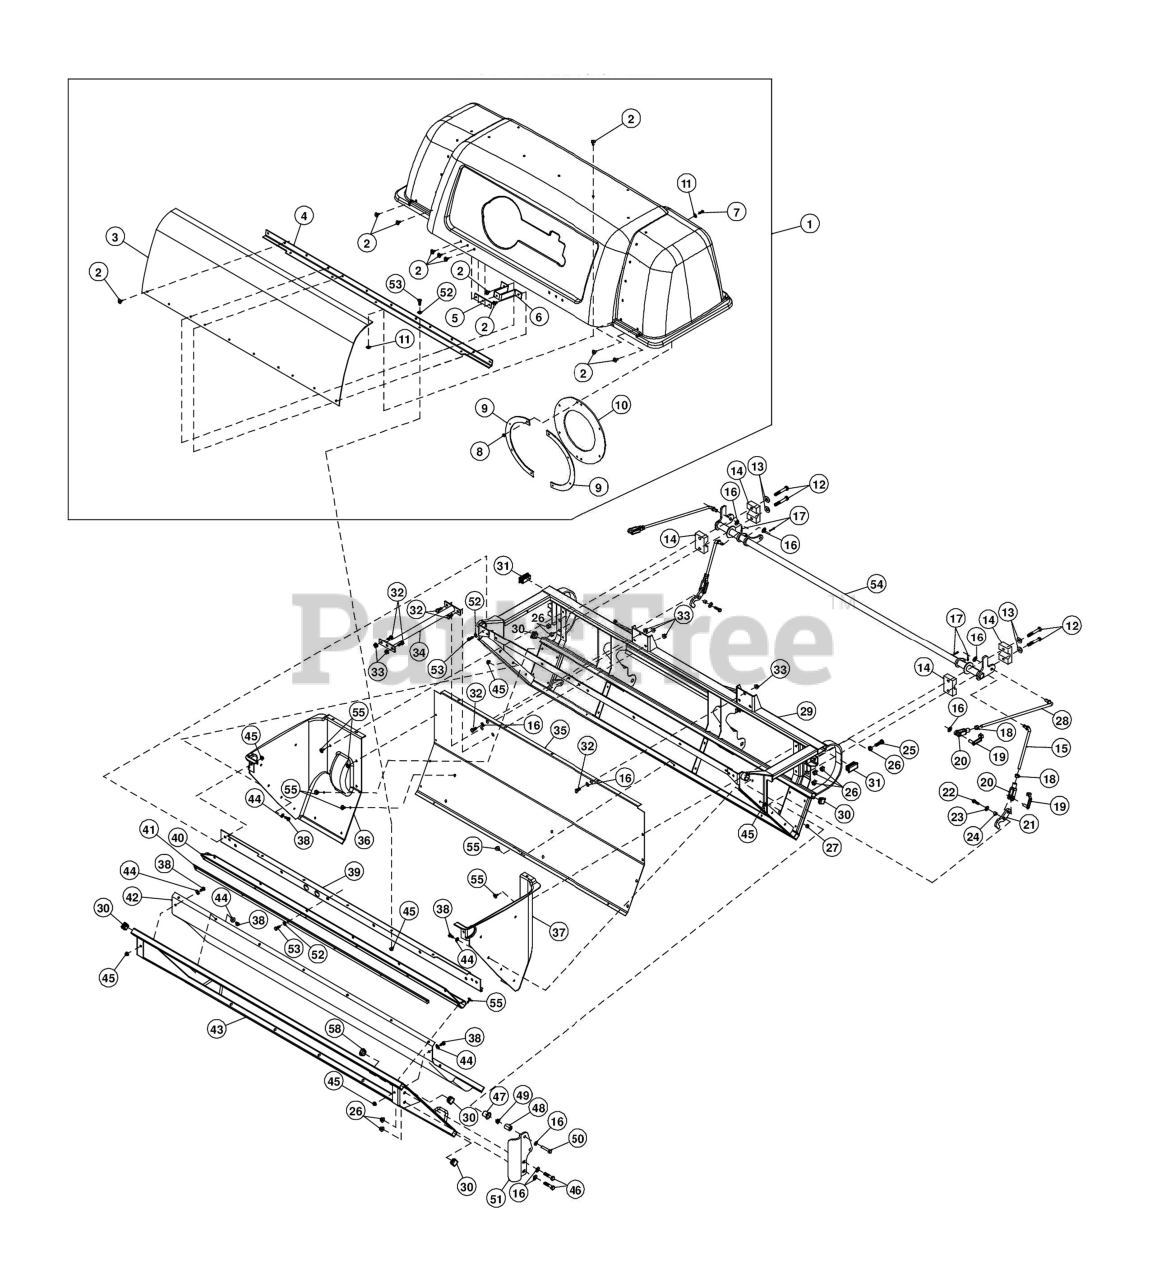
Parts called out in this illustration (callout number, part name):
1	ASM, HOOD - SERVICE ONLY
2	RIVET-BLIND
3	SCREEN-BAGGER
4	SUPPORT-SCREEN
5	PLATE-LATCH, REINFORCEMEN
6	BRACKET-MOUNT
7	SCREW-PPH
8	NUT-LOCK, NI
9	CLAMP-SEAL
10	SEAL-TUBE
11	WASHER-FLAT
12	SCREW-HH
13	WASHER-FLAT
15	LINK-HANDLE
16	WASHER-FLAT
17	PIN-COTTER
18	NUT-HEX
19	PIN-SPRING, CLEVIS
20	YOKE-LINKAGE, BRAKE
22	SCREW-HH
23	WASHER-FLAT
25	SCREW-HH
26	NUT-HHF, WHIZ
27	NUT-LOCK, NI
28	LINK-HINGE
29	UPRIGHT-BAGGER
32	SCREW-HH
35	SHEET-WALL
36	PANEL-BAGGER, LH
37	PANEL-BAGGER, RH
38	SCREW-HH
39	REAR CROSSMEMBER ASM
40	SEAL-DOOR HINGE
41	STRAP-HOLD DOWN
42	BAG AND BOTTOM PANEL ASM
43	DOOR ASM
44	WASHER-FLAT
46	SCREW-HH
47	BUSHING
48	PIN-PIVOT, HINGE
49	NUT-LOCK, NI
50	SCREW-HH
51	ARM-HINGE, LH
52	WASHER-FLAT
53	SCREW-HH
54	LINK-INTERMEDIATE
55	RIVET-BLIND
58	PLUG-DOME
